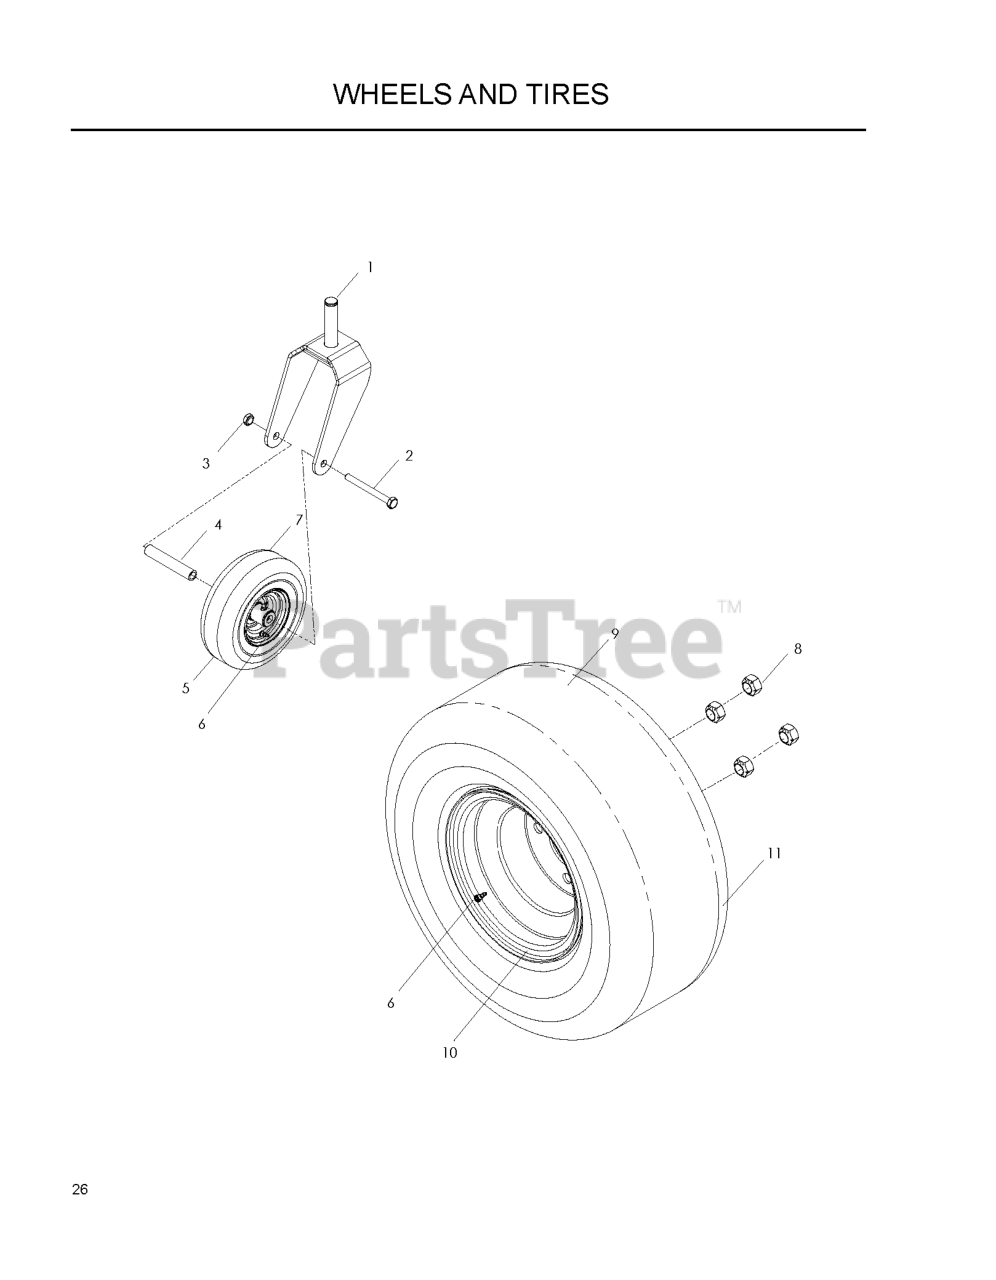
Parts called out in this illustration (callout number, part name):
1	CASTER WLDT
2	HCS 1/2C X 5 1/2
3	NUT 1/2-13 HEX NYLOC ZD
5	TIRE COMPLETE
6	VALVE STEM TR-412
7	TIRE - CASTER
8	LUG NUT 1/2F
9	TIRE ASM, 20X10-.8 NEG SILVER
10	RIM.8X7.W/8".OFFSET.SILVER.ZTR
11	TIRE, 20 X 10-8
